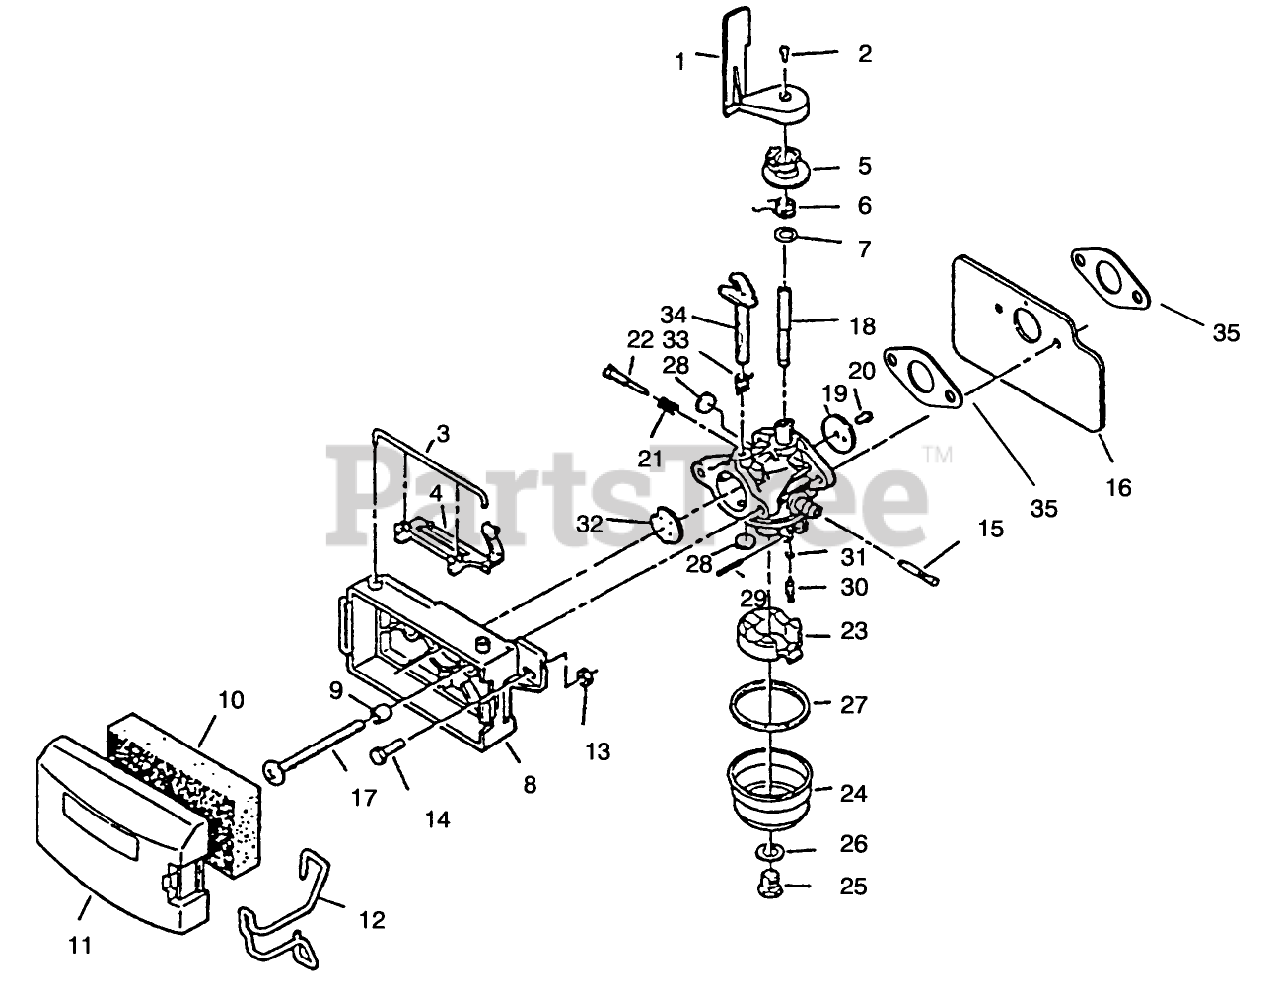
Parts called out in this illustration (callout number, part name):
1	AIR VANE F
2	SCREW F
3	RETAINER
5	COLLAR A/VAVE F
6	THROTTLE SPR E
7	WASHER VF
12	RETAINER-COVER, FILTER
15	SCREEN FUEL PITTS
16	SHIELD, CARB F
18	Shaft-Throttle
19	Vane-Throttle
21	Spring-Needle
22	Needle-Idle
24	Bowl-Fuel
26	Gasket-Bowl Retainer
27	Gasket-Bowl
28	Plug-Welch
29	Shaft-Float
30	Inlet-Needle Valve
31	Seat-Valve
32	Valve-Choke
33	Spring-Return
34	Shaft-Choke
35	GASKET CARB S
